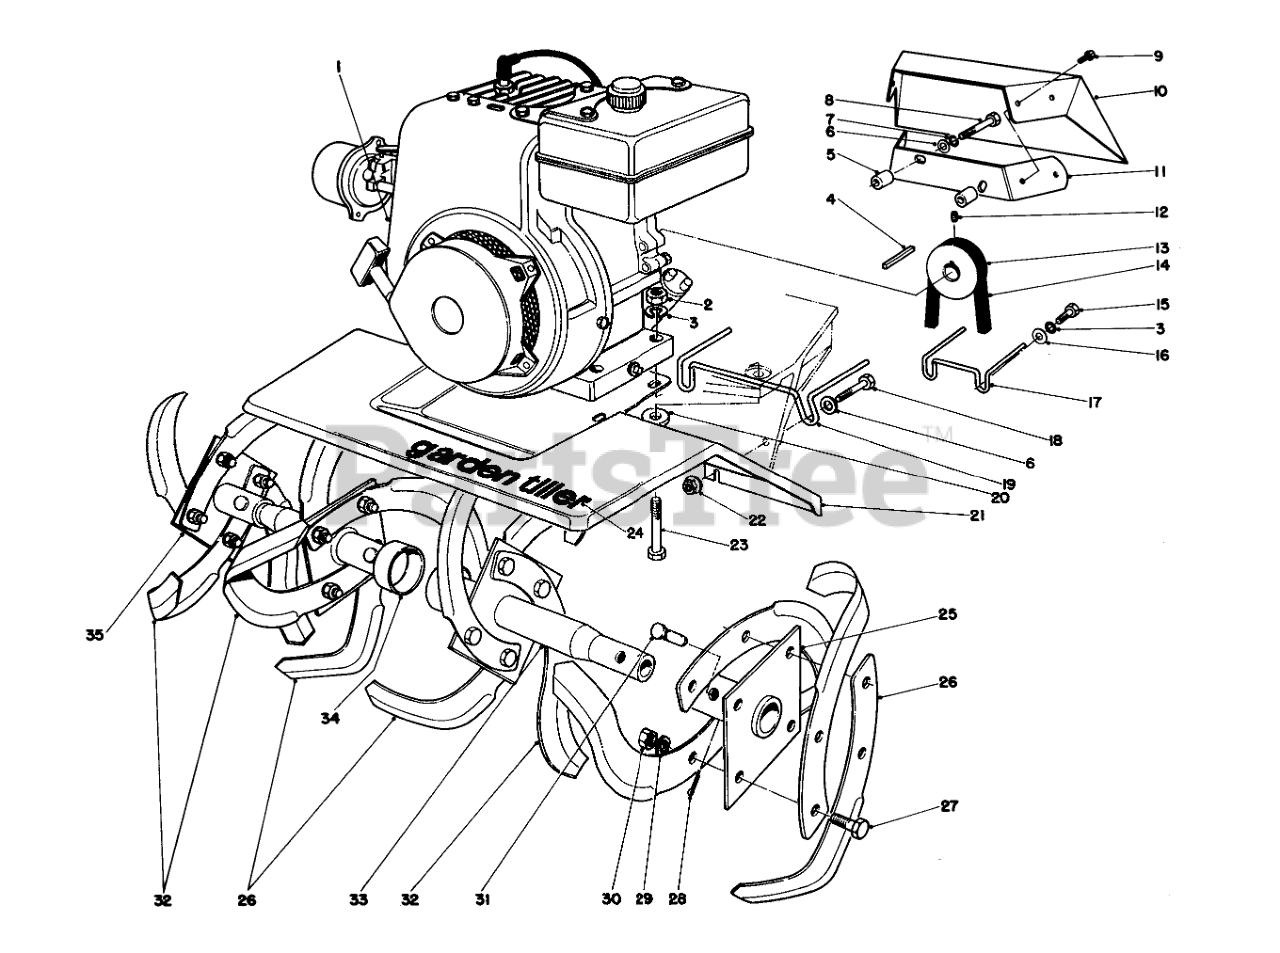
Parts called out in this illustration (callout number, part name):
1	Engine
2	NUT-HEX
3	WASHER-LOCK
4	KEY-SQUARE
5	Spacer
6	WASHER-FLAT
7	WASHER-LOCK
8	SCREW-HH
9	SCREW-HWHTF
10	PULLEY GUARD
11	Strap-Belt Shield
12	SCREW-HSH
13	Engine Pulley
14	V-BELT
15	SCREW-HH
16	WASHER-PLAIN
17	Belt Guide
18	SCREW-HH
19	BELT GUIDE
20	WASHER-FLAT
21	TINE SHROUD
22	NUT-LOCK, HHF
23	SCREW-HH
24	Decal
25	Axle L.H.Outer
26	RH TINE
27	SCREW-HH
28	PIN-COTTER
29	WASHER-LOCK
30	NUT-HEX
31	TINE PIN
32	LH TINE
33	Axle L.H. Inner
34	Axle R.H. Inner
35	Axle R.H. Outer
